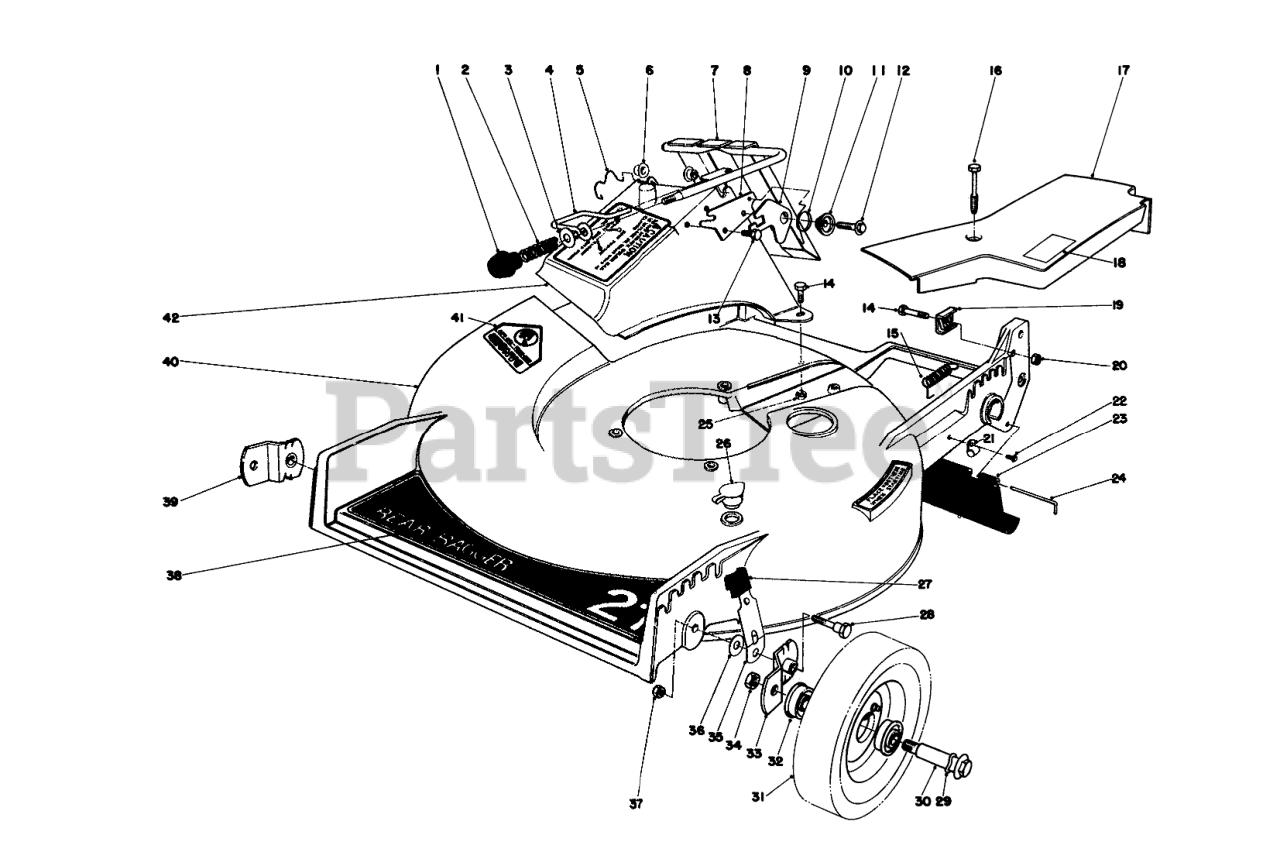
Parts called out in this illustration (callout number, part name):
2	COMPRESSION SPRING
3	WASHER
4	DOOR LATCH
5	DOOR RETAINER
6	BUSHING-NYLON
7	DOOR & HANDLE WA
8	DOOR LATCH PLATE
9	Latch Safety
10	TORSION SPRING
11	Latch Spacer
12	Screw
13	SCREW-HWH
14	SCREW-HH
15	IDLER SPRING
16	SCREW-HHFTF
17	Belt Cover
18	Sticker Grease
19	CLAMP-CABLE
20	NUT-JAM
21	CLAMP-NYLON
22	SCREW-HWH
23	Rear Safety Shield
24	Rod Shield
25	NUT-LOCK, NI
26	WASHOUT PLUG
27	KNOB-ARM
28	PIVOT SCREW
29	SPRING WASHER
31	Wheel & Tire Assembly (Incl. Ref. #32)
32	BEARING-BALL
33	PIVOT ARM ASM A
34	Nut
35	SPRING ARM ASM (R&S)
36	WASHER-PIVOT
37	Nut
38	Decal-Deck
39	PIVOT ARM ASM B
40	Housing
41	DECAL-DANGER
42	DISCHARGE CHUTE B
